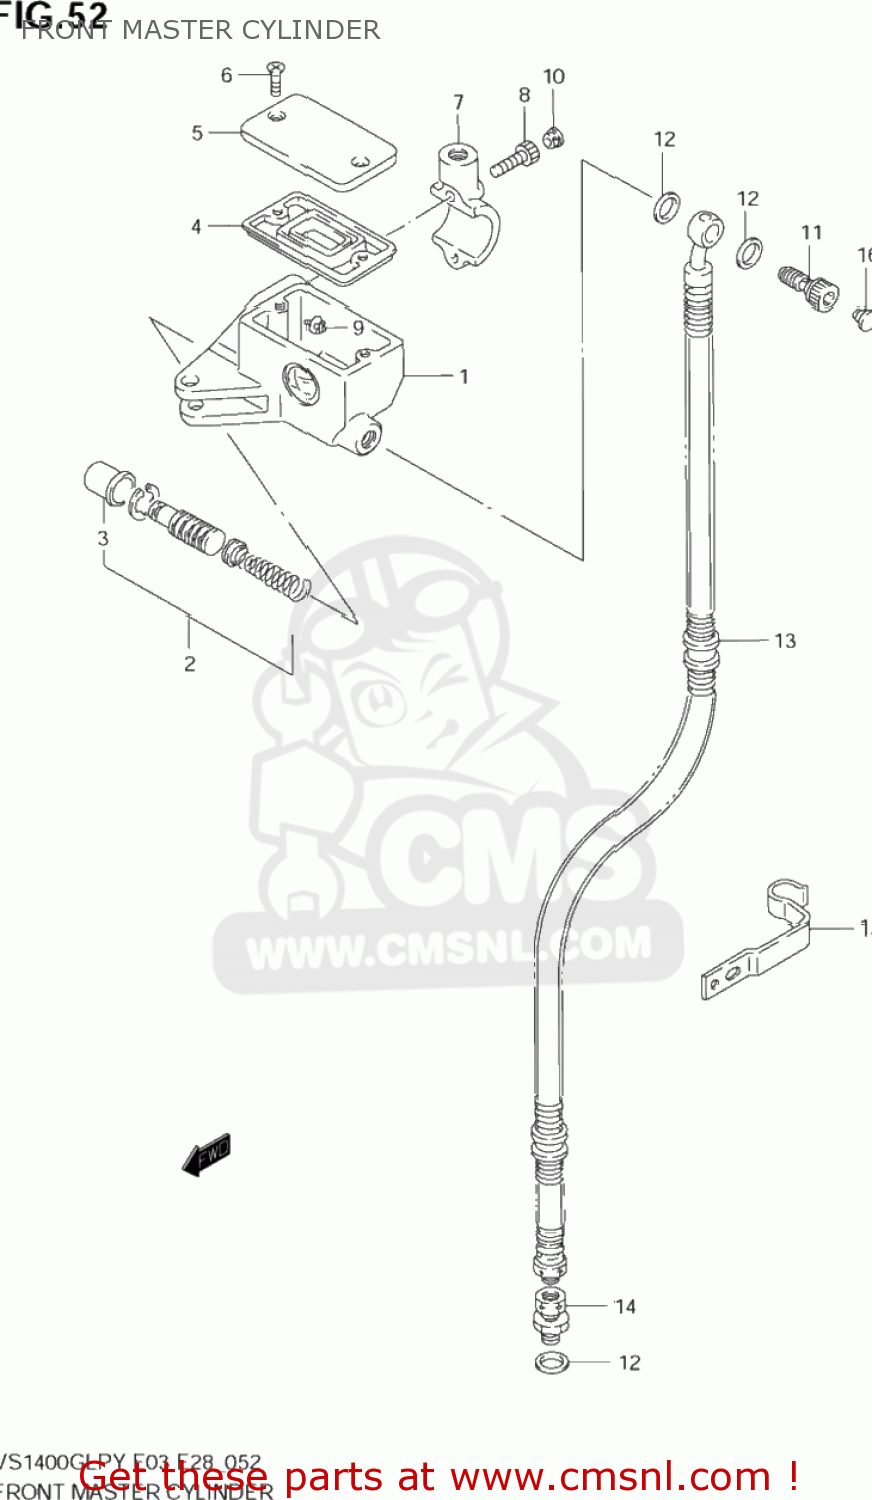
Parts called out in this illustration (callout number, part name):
1	CYLINDER ASSY,FR MASTER
2	PISTON/CUP SET
3	BOOT
4	5
5	CAP
6	SCREW
7	HOLDER
8	BOLT
9	PROTECTOR
10	CAP(OD:10)
11	BOLT UNION
12	WASHER(10X15X1.5)
13	HOSE,FR BRAKE
14	ADAPTER,BRAKE HOSE
15	GUIDE,BRAKE HOSE
16	CAP(OD:12)
